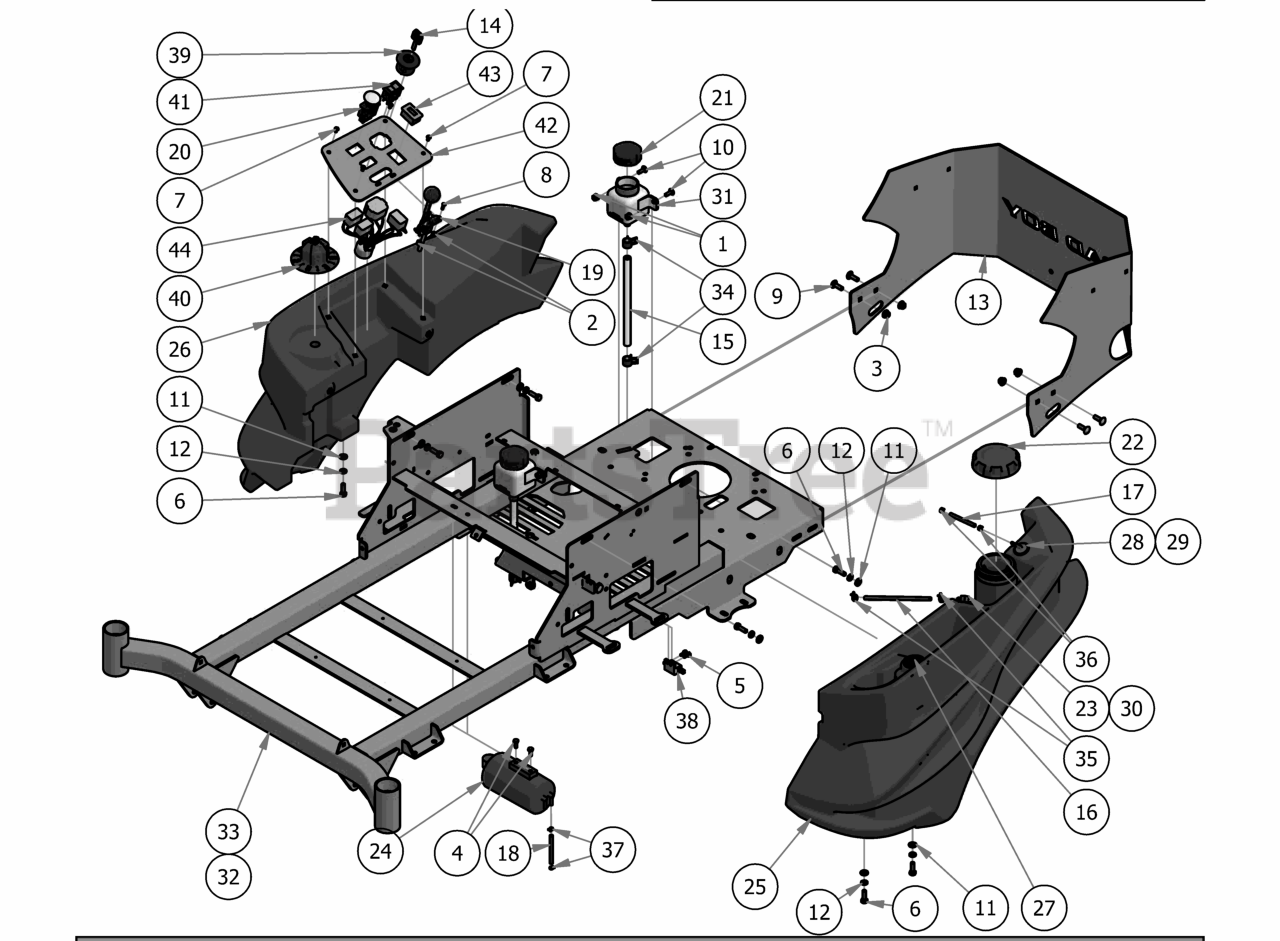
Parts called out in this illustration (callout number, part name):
1	1/4-20 Nylon Insert flange Nut
2	10-24 Nylon Insert Locknut Zinc Orange Nylon
3	5/16" Nylock Flange Nut Zinc
4	M6-1.0 X 16MM Hex Bolt
5	12-24x 1/2 HWH Bolt
6	5/16" x 1" Bolt
7	10-32 x 3/8" Button Socket Head Bolt
8	10-24 X 5/8 BS Button Head Bolt
9	5/16" x 1" Carriage Bolt
10	1/4" x 3/4" Carriage Bolt
11	5/16" Flat Washer
12	5/16" Lock Washer
13	2017 ZT Rear Plate
14	Ignition Key
15	3/8" Clear Hose
16	1/4" Fuel Line Hose
17	1/4" Vinyl Tubing
18	3/16 Vinyl Tubing
19	Throttle Lever Assembly
20	PTO Switch
21	Hydraulic Tank Cap
24	Carbon Canister
25	Left Fuel Tank
26	Right Side Console
27	Fuel Gauge w/Grommet
28	Rollover Valve
29	Rollover Valve Grommet
30	Pick-Up Grommet
31	350ml Expansion Tank
32	ZT 54" and 60" Frame
33	ZT 48" Frame
34	1/2 Hose Clamp
35	1/4 Fuel Hose Clamp
36	3/16 Vinyl Clamp
37	3/16" Vinyl Hose Clamp
38	Safety Switch
39	Ignition Switch
40	MZ/ZT Deck Height Dial
41	Rocker Deck Lift Switch
42	Control Panel
43	Tachometer
44	Universal Wire Harness
